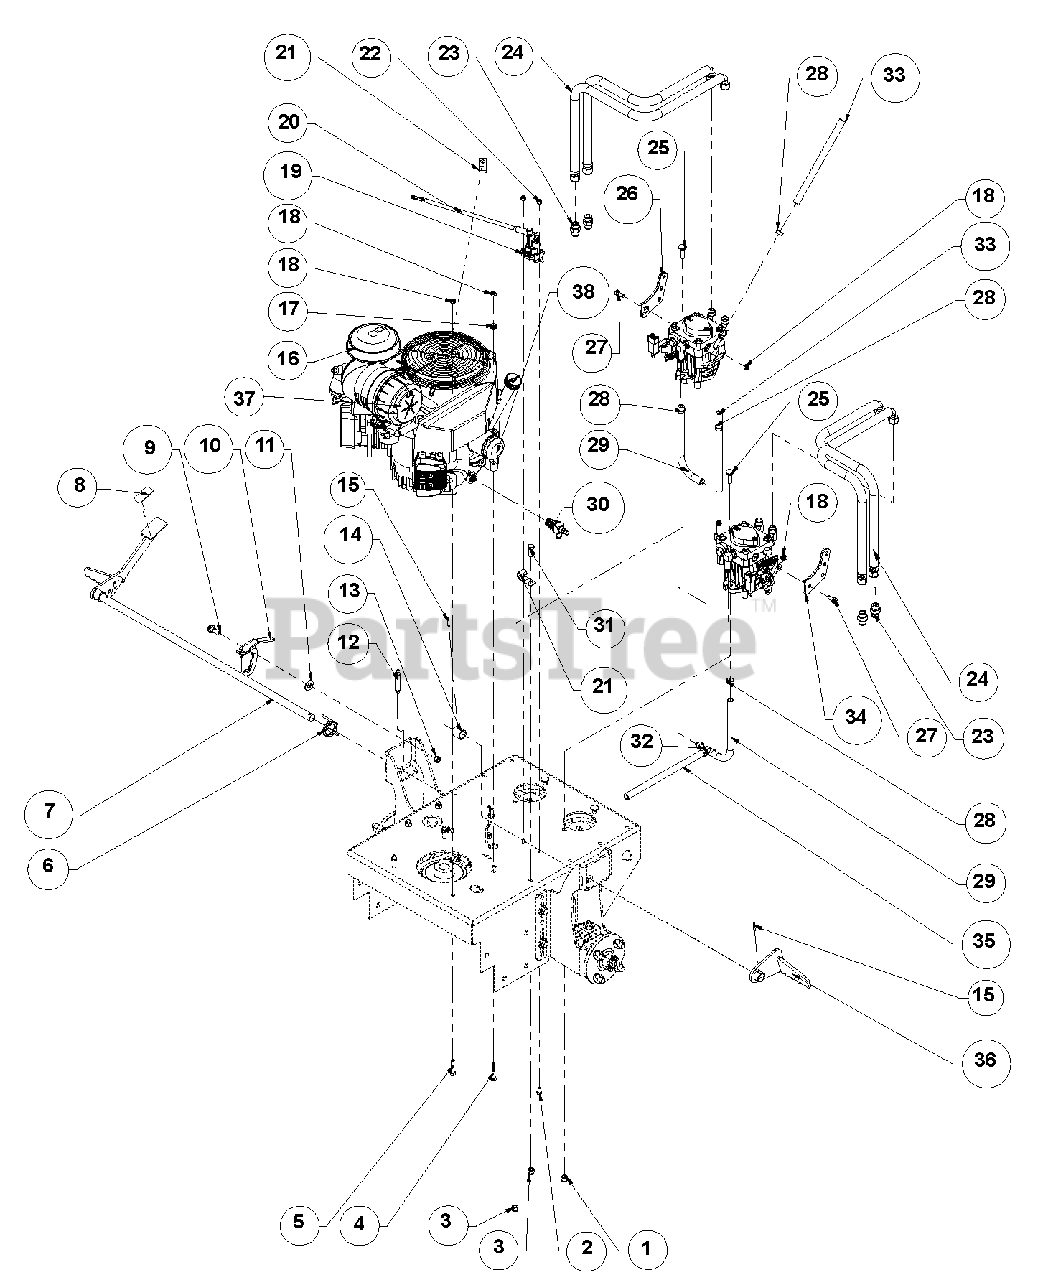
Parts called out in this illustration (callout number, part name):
1	Locknut, .38-16 Nyloc
2	Bolt, Hex .25-20 x .500 Grade 5 (402, 403)
3	Locknut, .38-16 Nyloc
4	Bolt, .3125-18 x 1.75 Hex 5
5	Bolt, .3125-18 x 1.50 Hex 5
6	Spring, RH Torsion Parking Brake
7	Weldment Brake System, By Bracket (400, 403)
8	Tape, Traction- 1.00 x 2.00
9	Bolt, .50 x 1.06 x .38-16 SLD 5
10	Latch, Brake CBMB
11	Washer, .500 x 1.00 x .105 Flat
13	Locknut, .38-16 Center
14	Bushing, 1.00 x .188 x 1.00
15	Pin, Spring
16	Engine, Kawasaki 19HP FH580V (402, 403)
17	Locknut, .3125-18 WHIZ
18	Locknut, .3125-18 Nyloc
19	Solenoid (402, 403)
20	Cable, 12" Starter (402, 403)
21	Pillow-Clip, .500 Insulated
22	Locknut, .25-20 Nyloc (402, 403)
23	Fitting, Straight
24	Hose, Hydraulic .50 x 26 .50 EZFLEX
25	Bolt, Round Head Square Neck .38-16 x 1.25
26	Weldment, CSWS Hydro Pump Arm
27	Bolt, .3125-18 x .750 Hex 5
28	Clamp, Hose- .50 Pinch
29	Hose, Hydraulic .38 x 6.00
30	Fitting, Oil Drain
31	Bolt, .38-16 x 1.00 Hex 5
32	Fitting, TUN .38 Hose
33	Hose, Hydraulic .38 x 9.5
34	Weldment, CSWS Left Hand Hydro Pump Arm
35	Hose, Hydraulic .38 x 11.00
36	Weldment, Left Hand Brake Arm
37	Air Filter (400, 403)
38	Oil Filter
